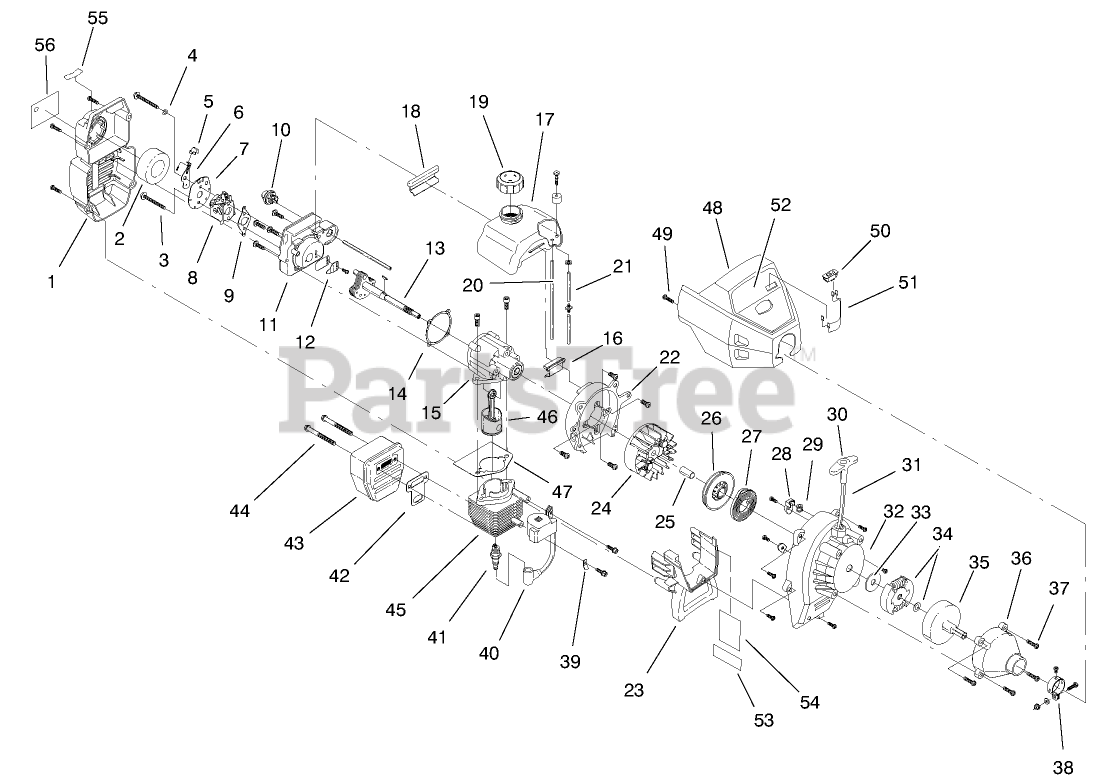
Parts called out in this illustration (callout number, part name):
1	Cover ASM (Includes Ref# 2)
2	FILTER - AIR CLEANER
3	ASSEMBLY - MOUNTING BOLT
4	WAVEY WASHER
5	Choke Lever ASM (Includes Ref #6)
6	CHOKE KNOB & SCREW (SERVICE)
7	Choke Lever & Plate (Includes Ref #5)
8	ASM-CARBURETOR MOUNT
9	CARBURETOR GASKET(10 PER PACK)
10	PRIMER & HOSE ASM
11	CARB. MOUNT ASM.
12	REED ASSEMBLY
13	ASM - POWER SHAFT
14	CARB MT GASKET (10-PK)
15	Crank Case ASM (Includes Ref #13)
16	FRONT MOUNTING PAD
17	Fuel Tank ASM (Includes Ref #19-21)
18	REAR MOUNTING PAD
19	FUEL TANK CAP
20	ASSEMBLY - RETURN LINE
21	FUEL LINE ASM
22	SHROUD ASM
23	SHROUD EXTENSION (SERVICE)
24	FLYWHEEL
25	SPACER
26	RECOIL PULLEY ASM
27	RECOIL SPRING
28	PULLEY RETAINER ASSEMBLY
29	ROPE GUIDE
30	HANDLE - STARTER
32	ASSEMBLY - STARTER HSG
33	CLUTCH WASHER
34	CLUTCH ROTOR ASM
35	CLUTCH DRUM ASM
36	CLUTCH COVER ASM
37	CLUTCH COVER SCREW ASM
38	CLAMP ASM - UPPER
39	GROUND TAB
40	MODULE ASM
41	SPARK PLUG
42	GASKET-EXHAUST (SERVICE)
43	Muffler ASM (Includes Ref #44)
44	MUFFLER MTG BOLT ASM
45	CYLINDER ASM
46	PISTON & ROD ASM
47	CYLINDER GASKET
48	COVER - ENGINE
49	Screw
50	SWITCH ASM
51	LEAD WIRE ASM
52	DECAL - TORO
53	Decal-Warning
54	DECAL-CARB (SERVICE)
55	Decal-Choke Position
56	Decal-Fuel & Oil Mix
